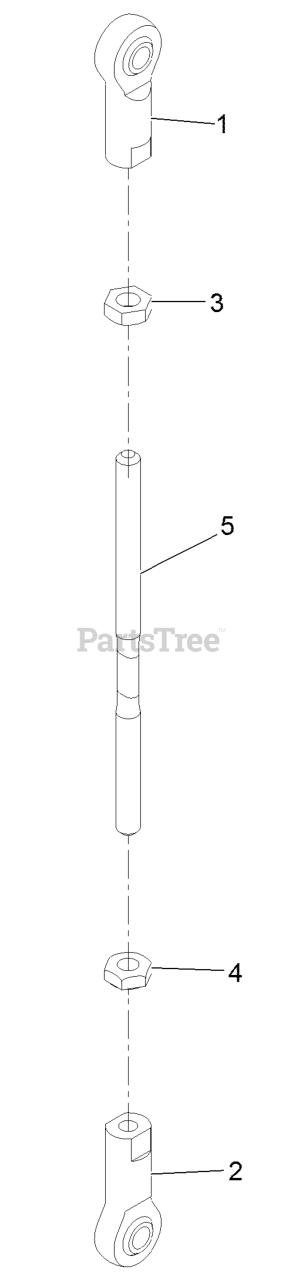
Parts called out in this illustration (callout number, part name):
1	ROD END-BALL JOINT
2	JOINT-BALL, LH
3	NUT-JAM
4	NUT-JAM
